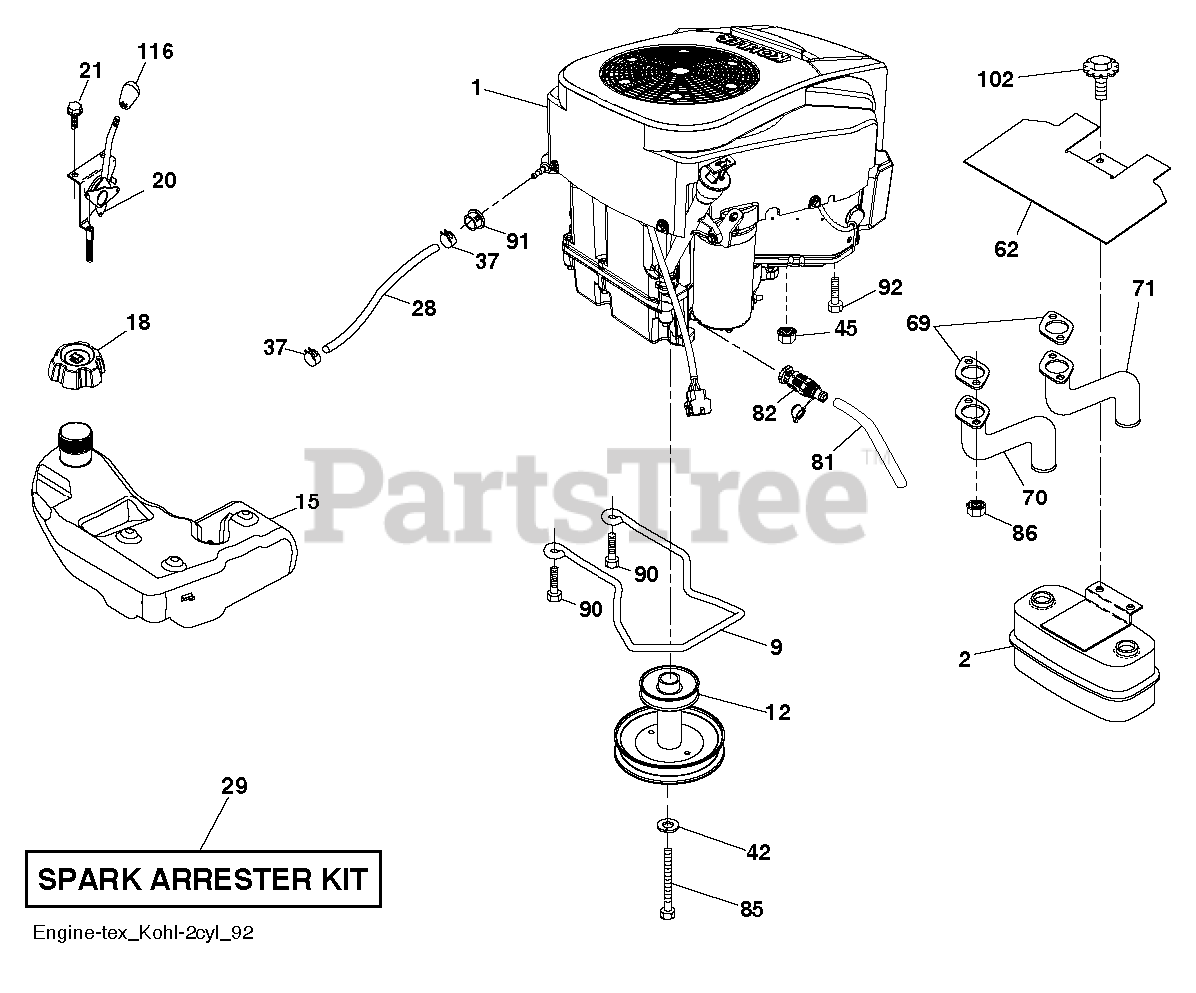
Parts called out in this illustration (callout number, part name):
2	MUFFLER.ASM.TWIN.MNTG.BRACKET
12	PULLEY.ENGINE
15	Tanks
18	CAP ASSY FUEL 3" GRAY
18	FUEL CAP
20	THROTTLE.KOHL.PRO.#88PAD_46"
21	SCREW.#10X.750
28	LINE.FUEL.64"REAR.EMIS
29	KIT.SPARK ARRESTOR 794945 B&S
37	HOSE CLAMP
62	SHIELD.HEAT.MUFFLER
69	GASKET.MUFFLER
70	PIPE.EXHAUST.LH.CV18/20
71	PIPE.EXHAUST.RH.CV18/20
81	TUBE, DRAIN OIL ASM.
82	VALUE.OIL.DRAIN
85	BOLT.HEX.7/16-20X4.GR5.1.5BLUE
86	NUT.HEX.FLANGE.TOPLOCK
90	SCREW 3/8-16X1
91	BUSHING.1.375OD
92	SCREW 3/8-16X1
102	SCREW
116	KNOB - SHIFT
